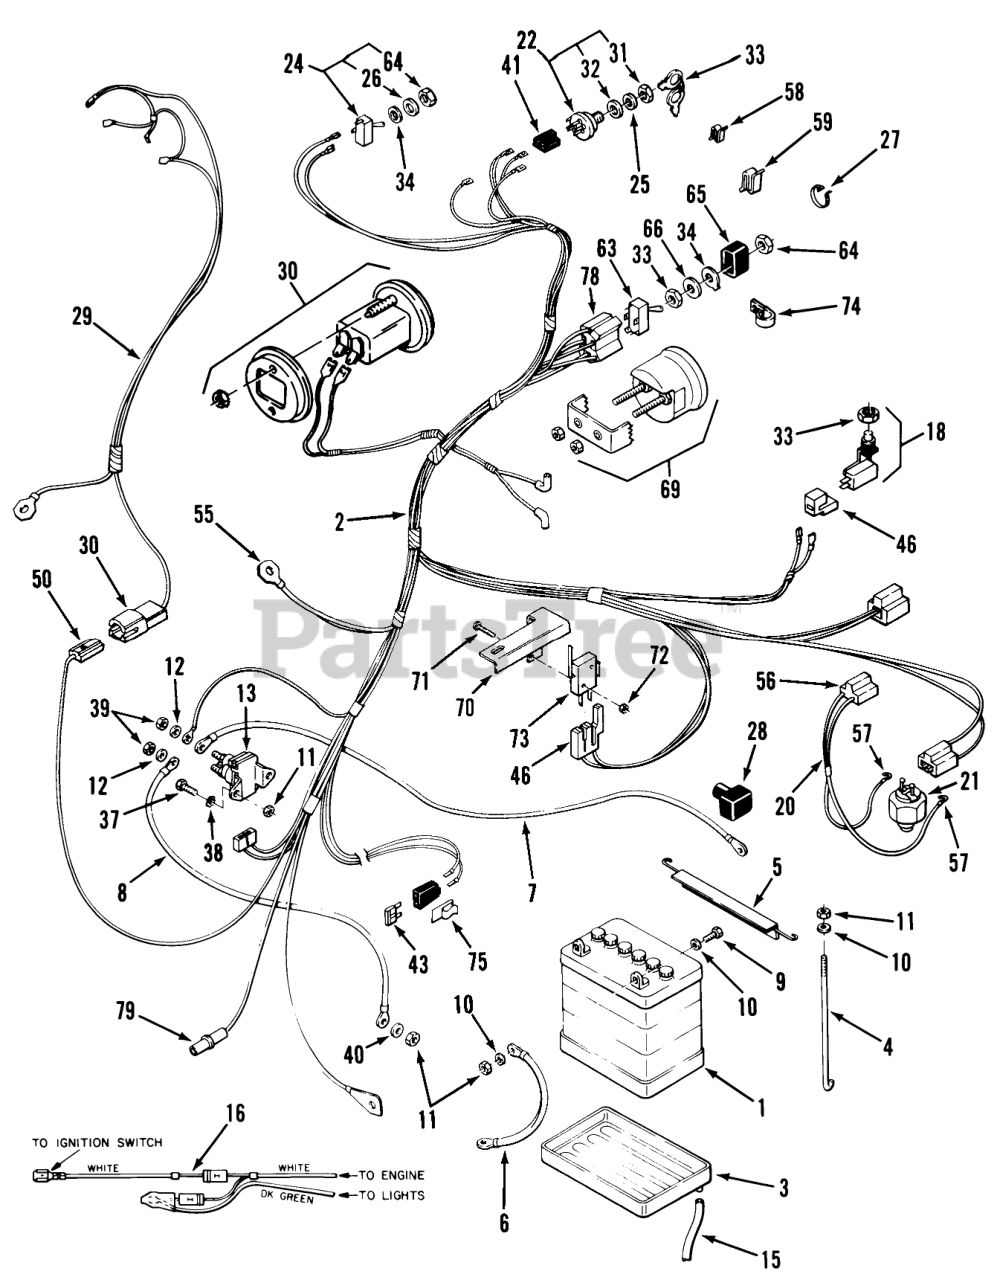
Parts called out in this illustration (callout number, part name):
2	WIRING-HARNESS & DIA
3	TRAY-BATTERY
5	HOLDDOWN-BATTERY
6	WIRE -BLACK
7	WIRE - 14" BLACK
15	TUBE-BATTERY DRAIN
16	DIODE-KIT SERVICE
20	ASSY WIRING HARNESS
21	SWITCH (N.C.-TRANS)
24	SWITCH-LIGHTS
26	Washer
30	GAUGE-HOURMETER
34	TAB-WASHER
43	FUSE-BLADE, 15 AMP
46	CONNECTOR BODY
50	CONNECTOR BODY ELECT
56	CONNECTOR BODY *B
57	TERMINAL-TAB RCPT
58	CLIP
63	Electric Clutch Switch (includes items 33, 34 64) 208, 211
64	*DISC**
65	COVER-PTO SWITCH
66	WASHER-FLAT
73	SWITCH
74	CLAMP
78	CONNECTOR 5 WAY
